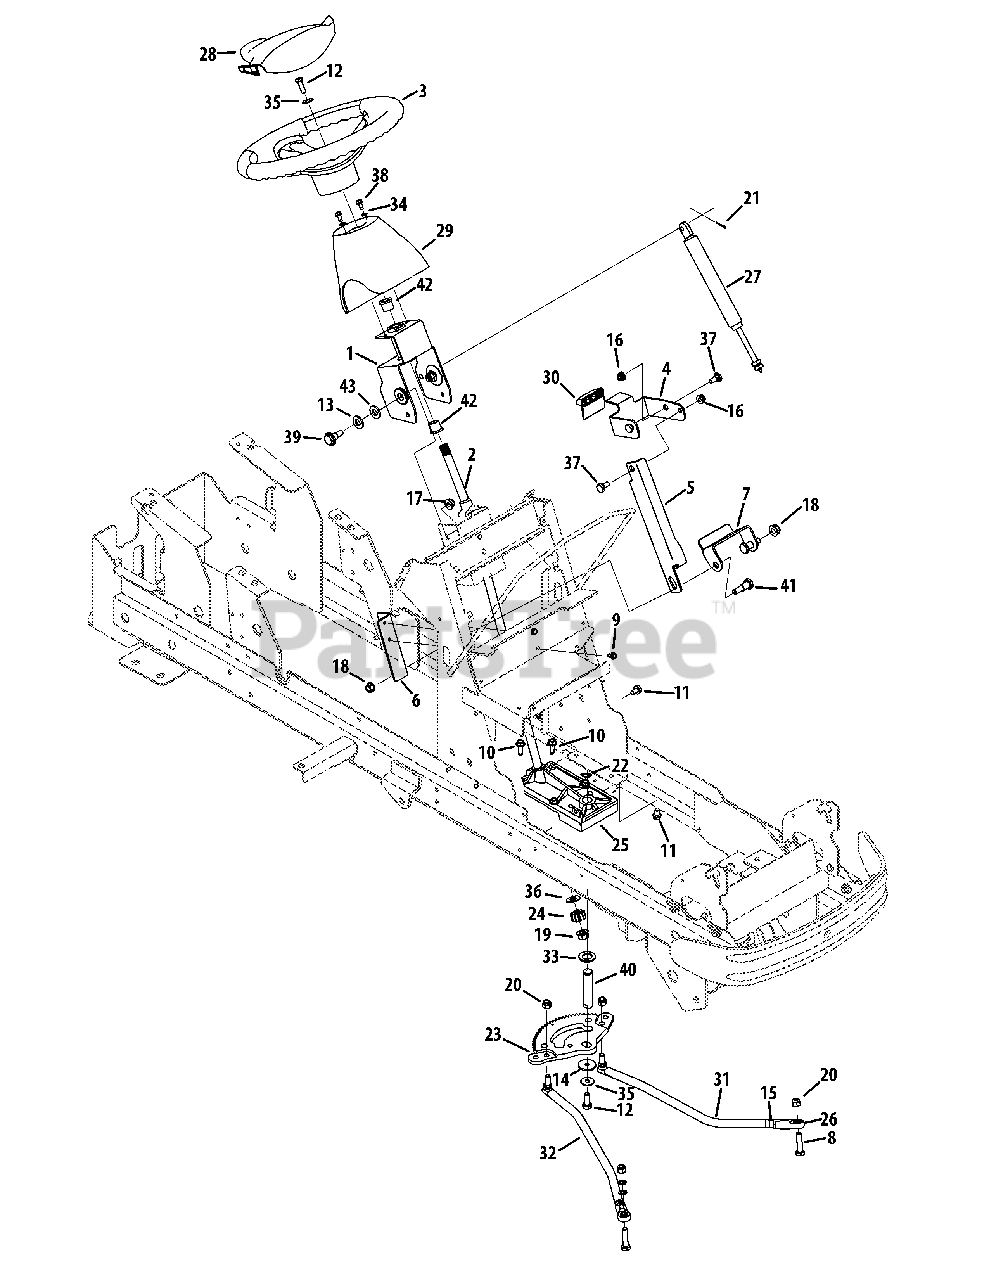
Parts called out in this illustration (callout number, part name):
1	Steering Upper Support Bracket
2	Manual Steering Assembly
3	Steering Wheel
4	Tilt Steering Lever Bracket
5	Tilt Steering Bracket
6	Tilt Steering Mount Bracket
7	Tilt Steering Pivot Bracket
8	Hex Screw, 3/8-24 x 2.00
9	Hex Washer Screw, 1/4-20 x .500
10	Hex Washer Screw, 5/16-18 x 1.000
11	Hex Washer Screw, 5/16-18 x .625
12	Hex Lock Screw, 5/16-18 x 1.00
13	Flat Washer, .510 x 1.14 x .040
14	Flat Washer, .340 x 1.50 x .150
15	Jam Nut, 7/16-20
16	Flange Lock Nut, 5/16-18
17	Flange Lock Nut, 3/8-16
18	Flange Lock Nut, 3/8-16
19	Flange Lock Nut, 7/16-20
20	Hex Lock Nut, 3/8-24
21	Cotter Pin, 3/32 x .750
22	Snap Ring, .750
23	Segment Gear
24	Pinion Gear
25	Steering Housing
26	End Rod, 7/16-20 x 3/8
27	Locking Damper Cylinder
28	Steering Wheel Cover
29	Dash Collar
30	Tilt Lever
31	LH Drag Link, 5/8
32	RH Drag Link, 5/8
33	Flat Washer, .76 x 1.25 x .10
34	Flat Washer, .344 x .62 x .033
35	Bell Washer, .340 x .872 x .060
36	Thrust Washer, .510 x 1.12 x .060
37	Shoulder Screw, .435 x .178-5/16 x .56
38	Shoulder Screw, 1/4-20 x 0.500
39	Shoulder Bolt, 3/8-16 x .49 x .33
40	Steering Shaft
41	Shoulder Screw, 3/8-16 x .50 x .66
42	Flange Bearing, .630
43	Flat Washer, .580 x 1.125 x .080
